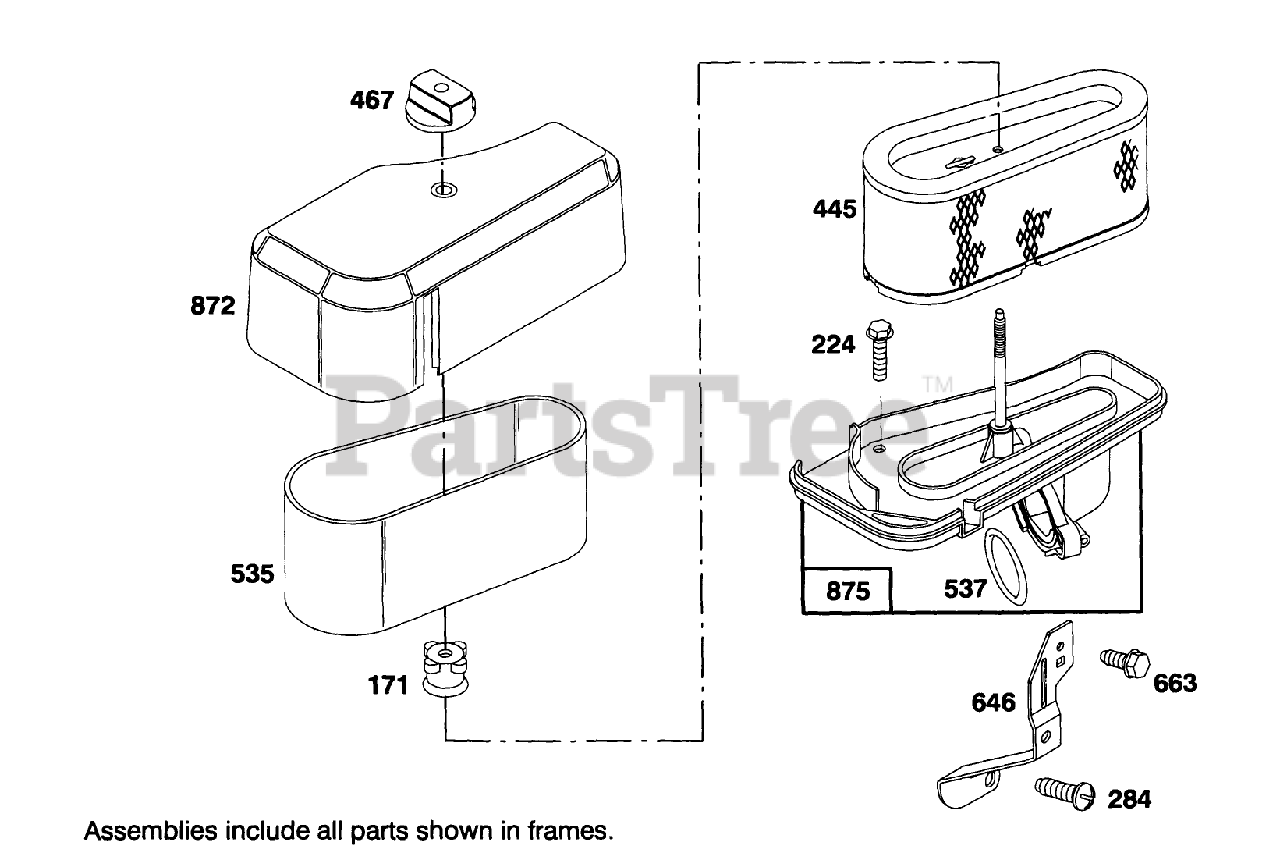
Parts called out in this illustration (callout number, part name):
224	Screw-Sem
284	Screw-Pan Head
445	Filter-Air
535	Filter-Air
537	O-Ring
646	Brace-Air Cleaner
663	Screw
872	Cover-Air Cleaner
875	Base-Air Cleaner
